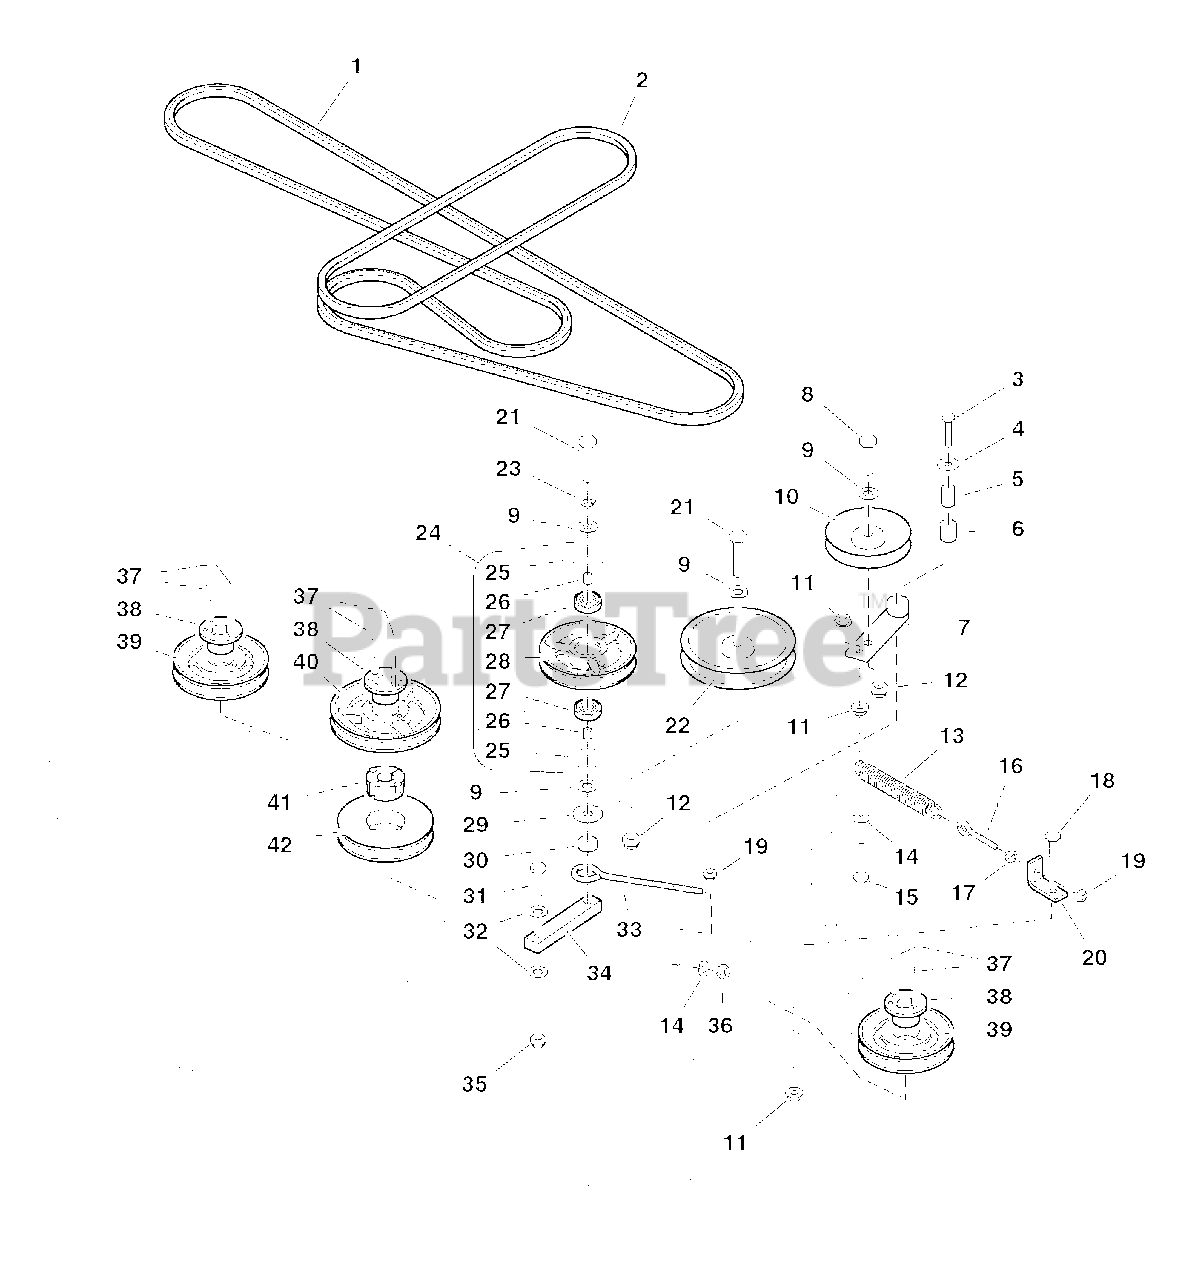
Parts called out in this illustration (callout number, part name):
1	BELT, Spindle Drive
2	BELT, Deck Drive
3	CAPSCREW, Hex Hd, 5/16-18 x 1-3/4
4	WASHER, Fender, 5/16
5	SPACER, Pivot
6	BUSHING, Brass
7	IDLER ARM, Complete (includes Ref 6)
8	CAPSCREW, Hex Hd, 1/2-20 x 2
9	WASHER, 1/2
10	PULLEY, Idler, V
11	NUT, Hex, Serrated Flange, 3/8-16
12	NUT, Hex, Nylon Lock, 1/2-20
13	SPRING, Extension
14	WASHER, 3/8
15	CAPSCREW, Hex Hd, 3/8-16 x 2
17	NUT, Hex, 5/16-18
18	CAPSCREW, Hex Hd, 3/8-16 x 1
19	NUT, Hex, Nylon Lock, 5/16-18
20	SPRING ANCHOR
21	CAPSCREW, Hex Hd, 1/2-20 x 2-1/4
22	PULLEY, Idler, Flat
23	WASHER, Lock, 1/2
24	IDLER PULLEY, Complete (includes Ref 25-28)
25	SNAP RING
27	BEARING, BALL 11/16X1-9/16X15/32
28	PULLEY, Idler
29	WASHER, USS, 1/2
30	SPACER, Pulley
31	CAPSCREW, Hex Hd, 7/16-20 x 1-3/4
32	WASHER, 7/16
35	NUT, Hex, Nylon Lock, 7/16-20
36	NUT, Hex, Nylon Lock, 3/8-16
37	BOLT, 1/4-20 X 1", GD
38	BUSHING, Taper Lock
39	PULLEY, Spindle
40	PULLEY, Spindle
41	BUSHING, Taper Lock
42	PULLEY, Taper Lock
